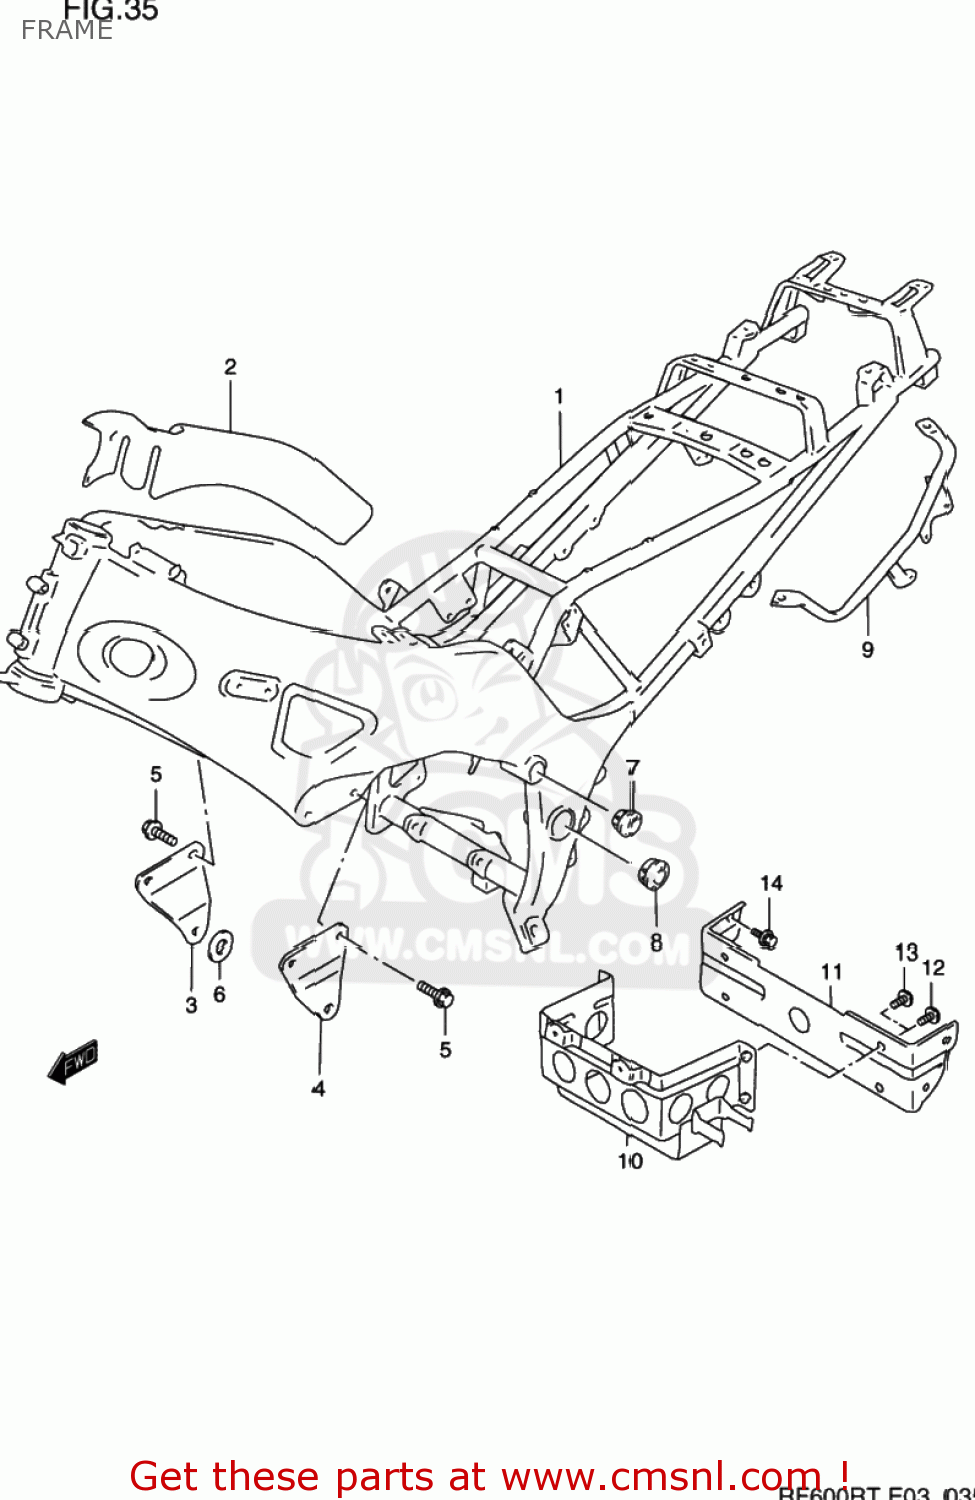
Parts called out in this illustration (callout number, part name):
1	FRAME COMP
2	SHIELD,FRAME HEAT,RIGHT
3	PLATE,ENGINE MOUNT,R
4	PLATE,ENGINE MOUNT,L
5	BOLT
6	WASHER (10.5X38X1.6)
7	CAP,FRAME BOSS,L
8	CAP,FRAME PIVOT
9	GRIP COMP,REAR,LEFT
10	HOLDER,BATTERY
11	BRACKET,BATTERY HOLDER
12	SCREW 6X12
13	BOLT
14	BOLT
